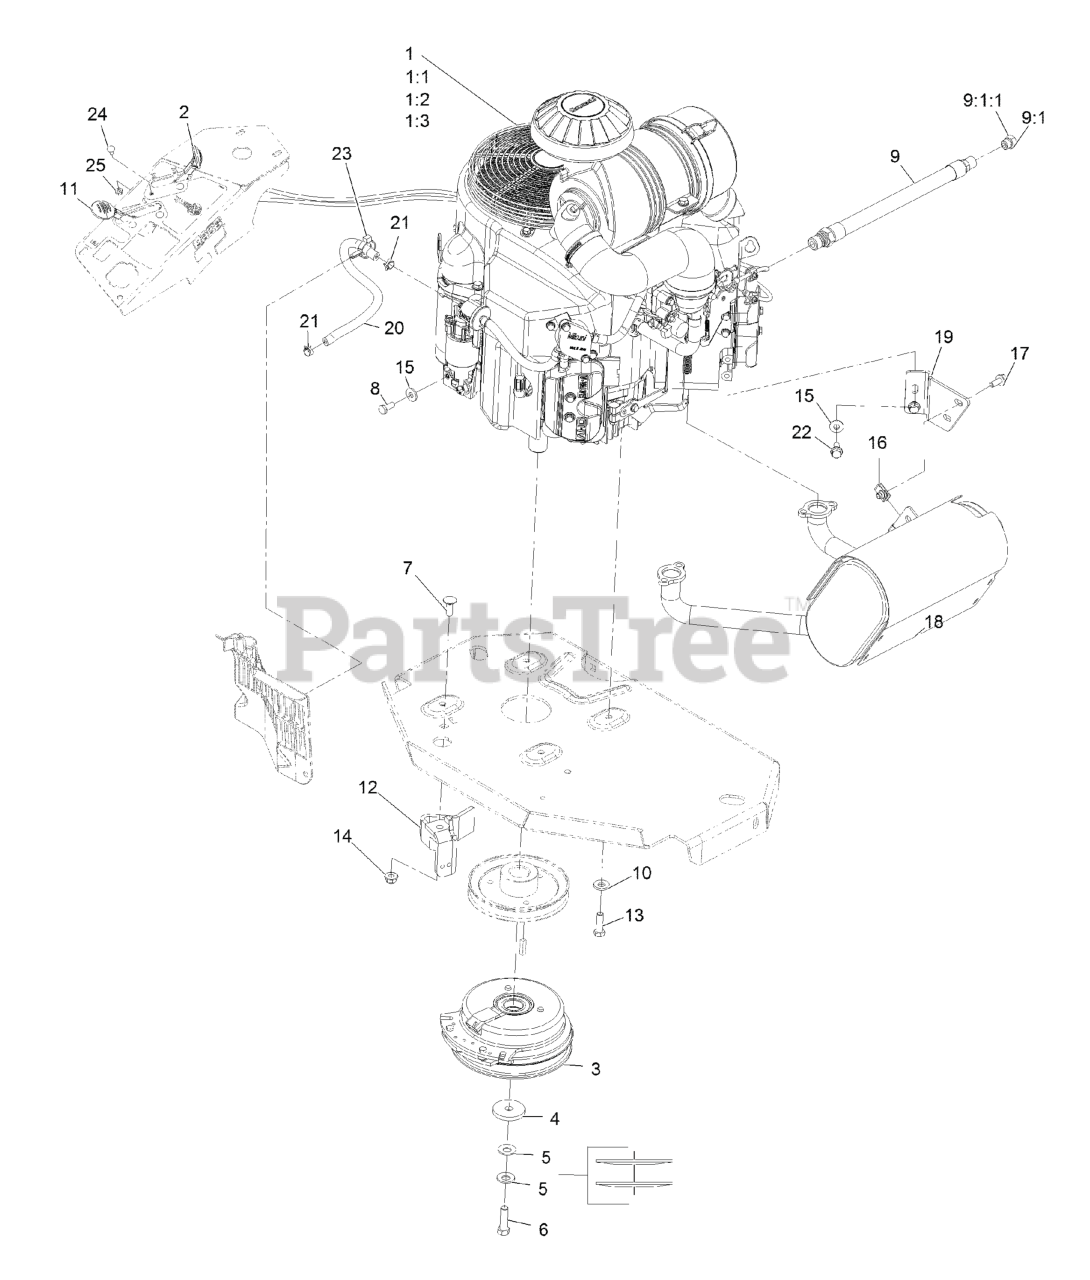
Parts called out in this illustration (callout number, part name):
1:1	Kawasaki 49065-2078 Engine Oil Filter
1:2	Kawasaki 11013-7044 Engine Air Filter
1:3	Kawasaki 11013-7045 Safety Filter
2	ASM, CHOKE CABLE
3	CLUTCH KIT
4	WASHER-CLUTCH
5	WASHER-SPRING
6	SCREW-HH 7/16-20 X 1 1/2 W/LOCTITE
7	SCREW-CARR
8	SCREW-HH
9	ENGINE OIL DRAIN HOSE ASM
9:1	PLUG-HH
9:1:1	O-RING
10	WASHER-BELLEVILLE
11	ASM,THROTTLE CABLE
12	CLUTCH-ANCHOR
13	SCREW-HH
14	NUT-HF, NI
15	WASHER-SPRING
17	SCREW-HHF
18	MUFFLER
19	BRACKET-MUFFLER
20	HOSE-FUEL
21	CLAMP-HOSE
22	SCREW-HHF
23	CLAMP-HOSE
24	BOLT-CARR
25	NUT-LOCK, NI
